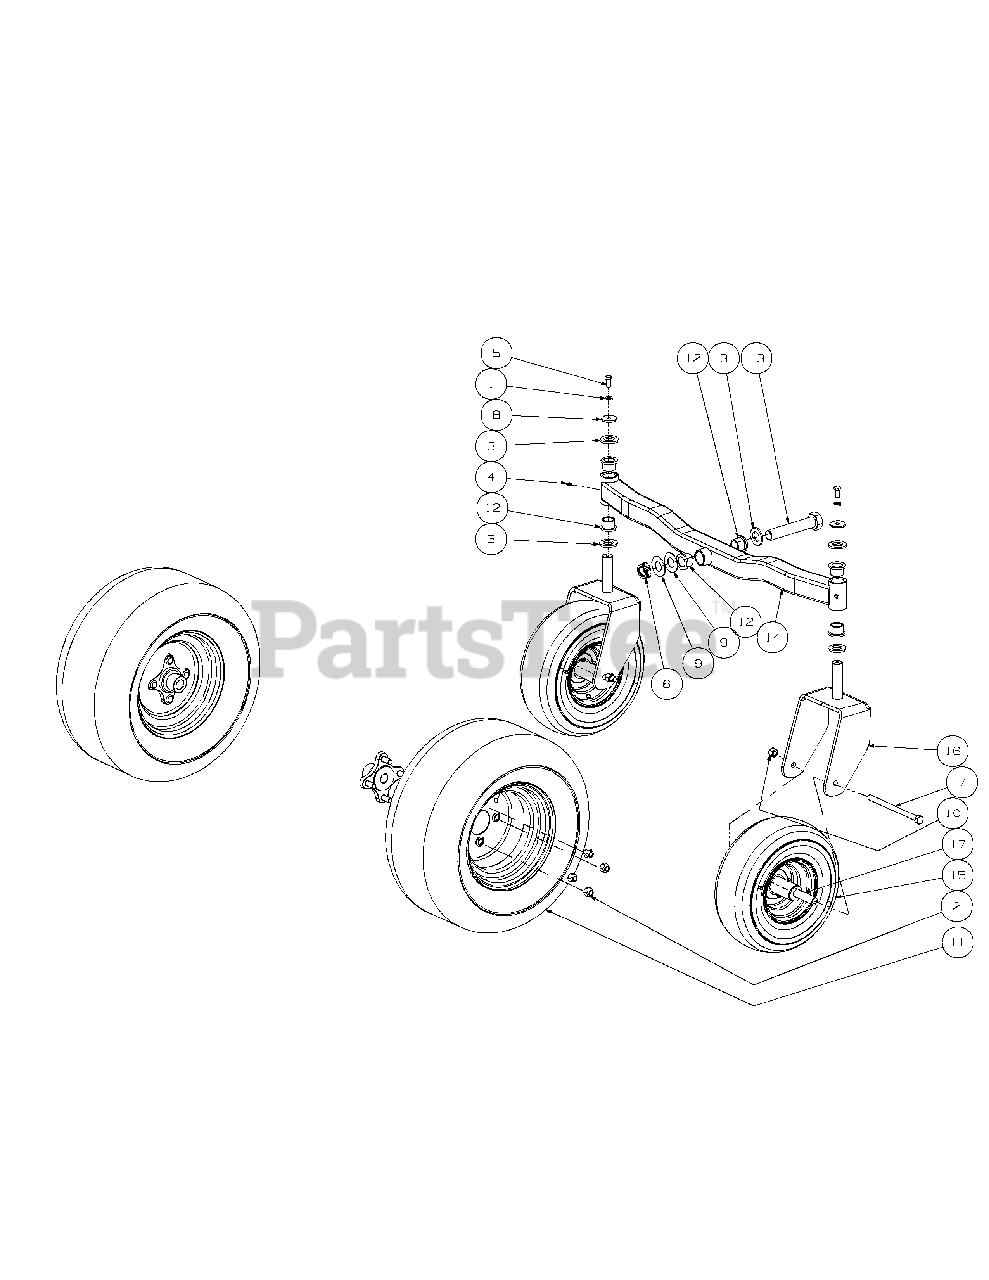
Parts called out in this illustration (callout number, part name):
1	Lock Washer, 3/8 Zinc
2	Lug Nut, 1/2-20
3	Washer Special
4	Grease Fitting, 1/4-28 x 3/16
5	Hex Cap Screw, 3/8-16 x .88
6	Nut Jam, 1.0-14, Nylon Insert
7	Hex Cap Screw, 1/2-20 x 7.50
8	Flat Washer, .390 x 1.5 x .134
9	Flat Washer, 1.00 ID x 2.25 OD x ,075
10	Lock Nut, Nylon Insert, 1/2-20
11	Wheel Assembly, 20 x 10.00 x 10
12	Flange Bearing, 1.001 x 1.25
13	Hex Cap Screw, 1-14 x 5.5
14	Front Axle Assembly
15	Wheel Assembly 13 x 5.00 - 6, Beige
16	Castor Wheel Mounting Bracket
17	Wheel Spacer
